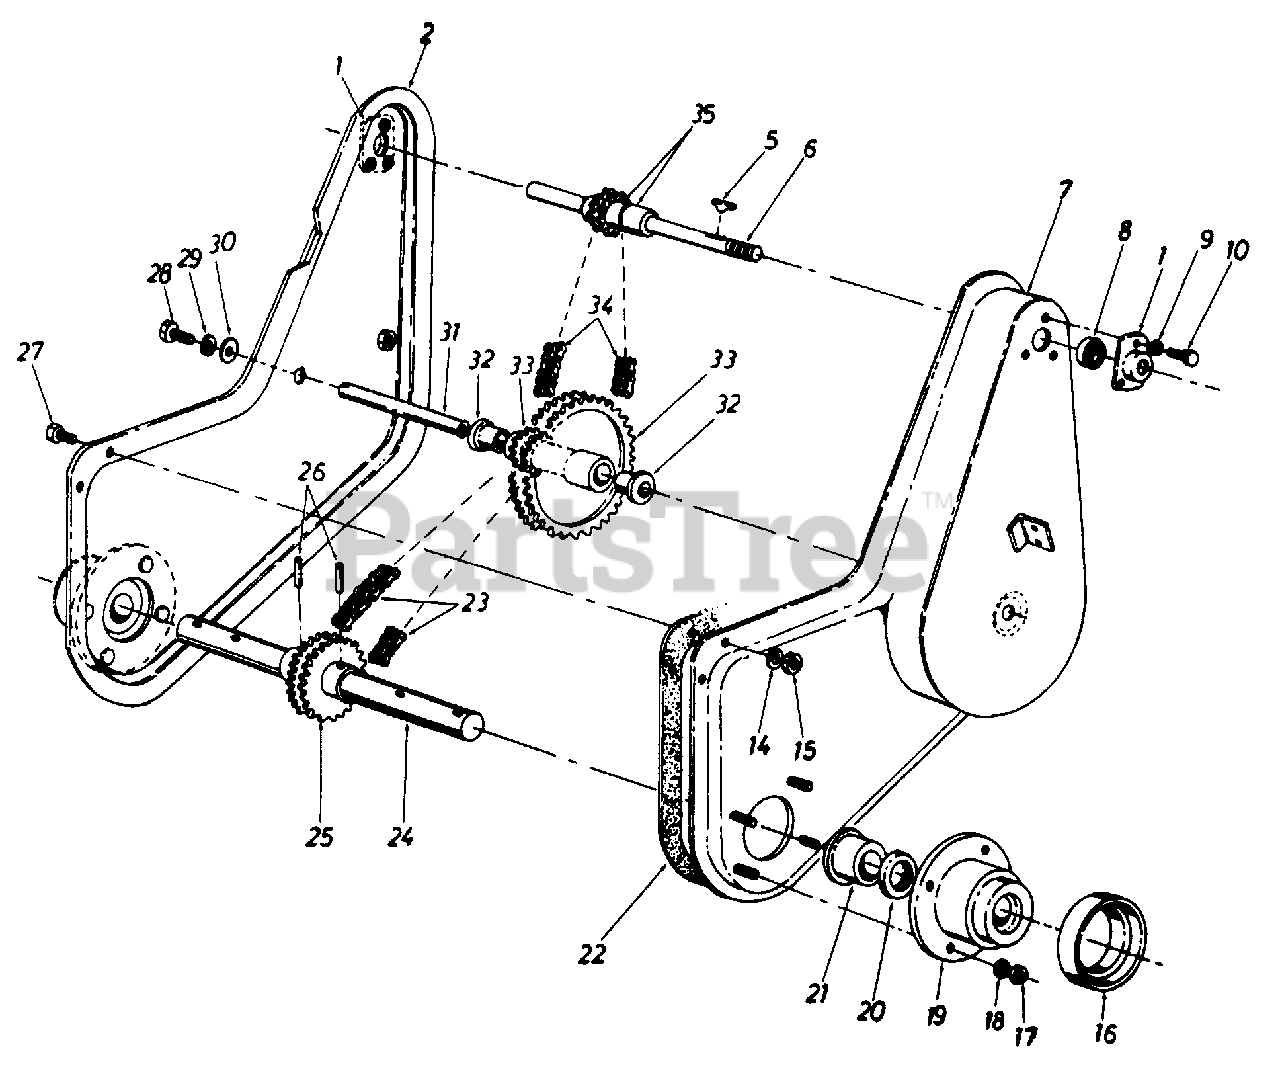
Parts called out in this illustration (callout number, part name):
1	Bearing Housing l.375" Dia.
6	Input Shaft Assembly
9	L-Wash. 1/4" I.D.
10	Hex Bolt 1/4-20 x .62" Lg.
14	L-Wash. 1/4" I.D.
15	Hex Cent. L-Nut 1/4-20 Thd.
16	Dust Cap Cover
17	Hex Cent. L-Nut 5/16-18 Thd.
18	L-Wash. 5/16" I.D.
19	Cast Bearing Housing
20	Oil Seal
21	Flange Bearing 1.25" I.D. x 1.75" O.D.
22	Gasket
23	Roller Chain #40-2 x 34.0" Lg.
24	Tine Shaft
25	Double Sprocket T242 Teeth 1/2" Pitch
26	Spiral Pin 3/8" Dia. x 2.00" Lg.
27	Hex Bolt 1/4-20 x .62n Lg.
28	Hex Bolt 5/16-18 x 75" Lg.
29	L-Wash. 5/16" I.D.
30	Fl-Wash. 5/16" I.D.
31	Sprocket Shaft
32	Flange Bearing .62" I.D. x 75" O.D.
33	Double Sprocket Assembly
34	Roller Chain #35-2 x 36.75" Lg.
35	Spacer 5/8" I.D. x 7/8" O.D.
